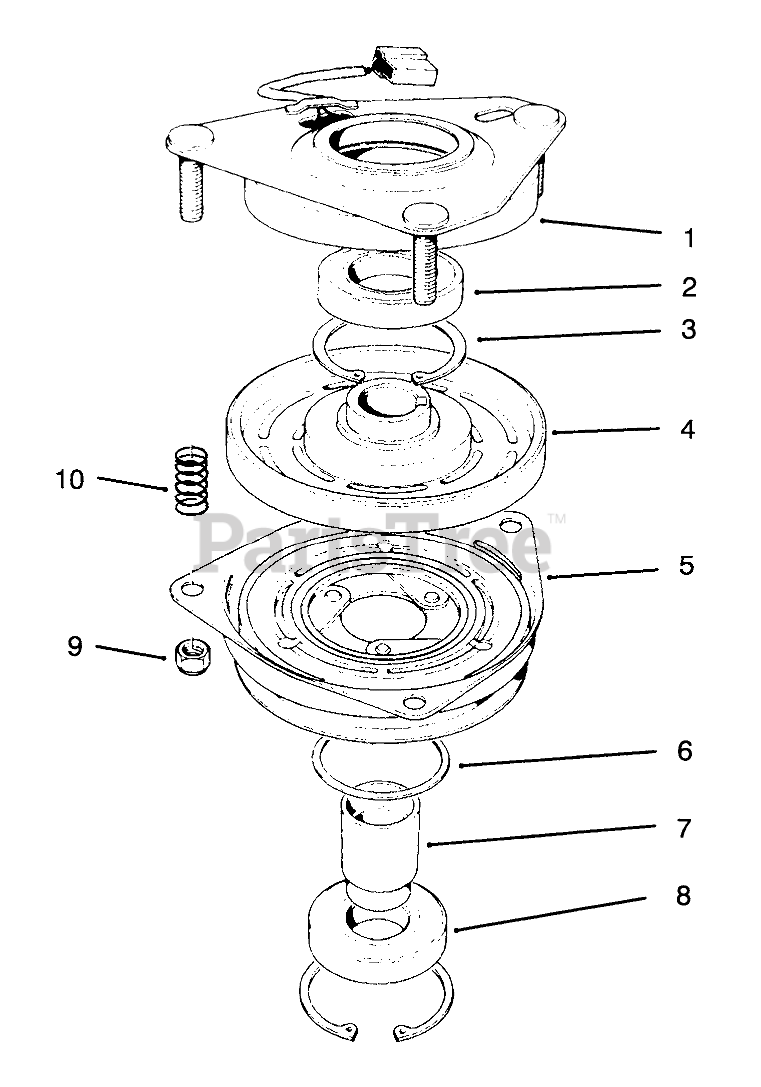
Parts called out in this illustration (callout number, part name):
1	Field Ass-y (Incl. Ref.#2 & 3)
2	BEARING-FIELD
3	RING-RETAINING
4	Field Coil,Rotor & Bearing Assembly (Incl. Ref. #1)
5	Armature & Pulley Assemble(Incl. Ref. #3,6,7,8)
6	SPACER-BEARING, PULLEY
7	COLLAR-BEARING
8	BEARING-PULLEY
9	NUT-HEX
10	SPRING
